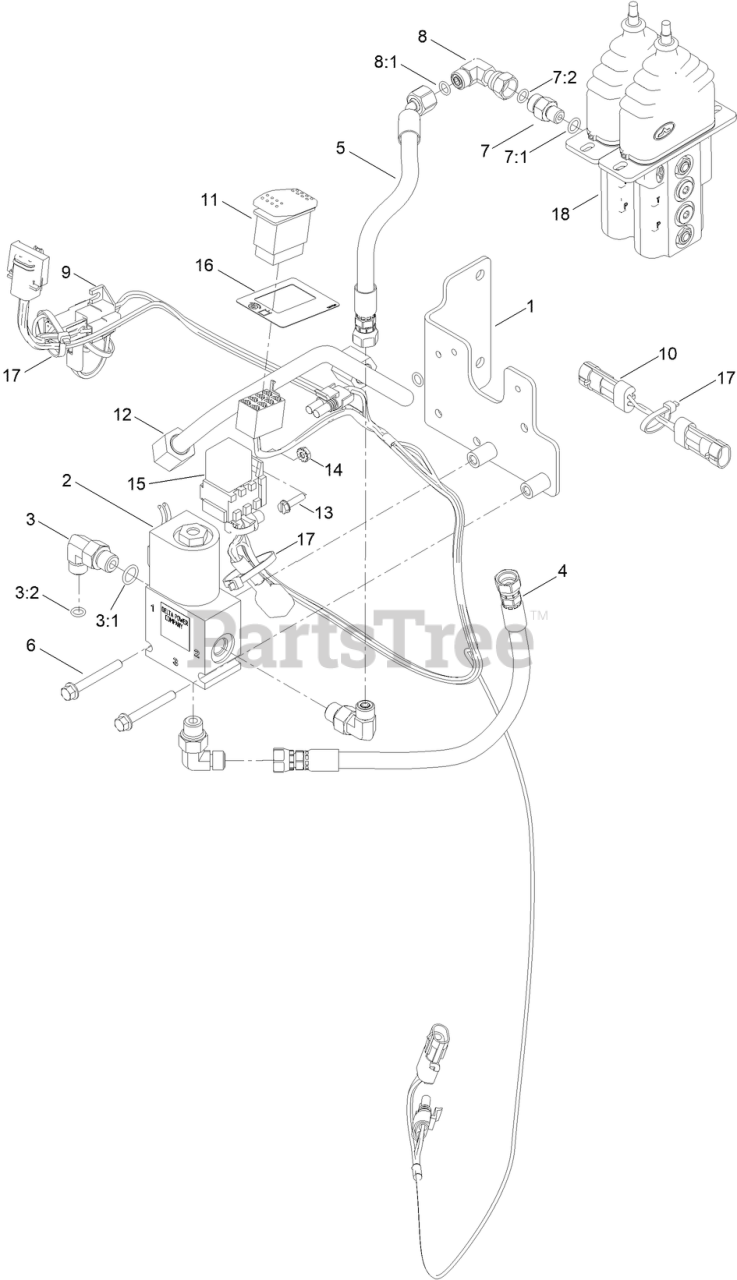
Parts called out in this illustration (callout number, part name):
2	SOLENOID VALVE
3	FITTING-ELBOW, 90 DEG
3:1	O-RING
3:2	O-RING
4	HOSE ASM
5	HOSE ASM
6	SCREW-HHF
7	FITTING-STRAIGHT
7:1	O-RING
7:2	O-RING
8	FITTING-ADAPTOR
8:1	O-RING
9	HARNESS-WIRE, TRACTION ENABLE
10	HARNESS-WIRE, TRACTION ENABLE JUMPER
11	SWITCH-INTERMITTENT
12	HYDRAULIC TUBE ASM
13	SCREW-HWH
14	NUT-KEPS
16	DECAL, TRACTION
17	TIE-CABLE
18	VALVE-CONTROL (TRACTION)
